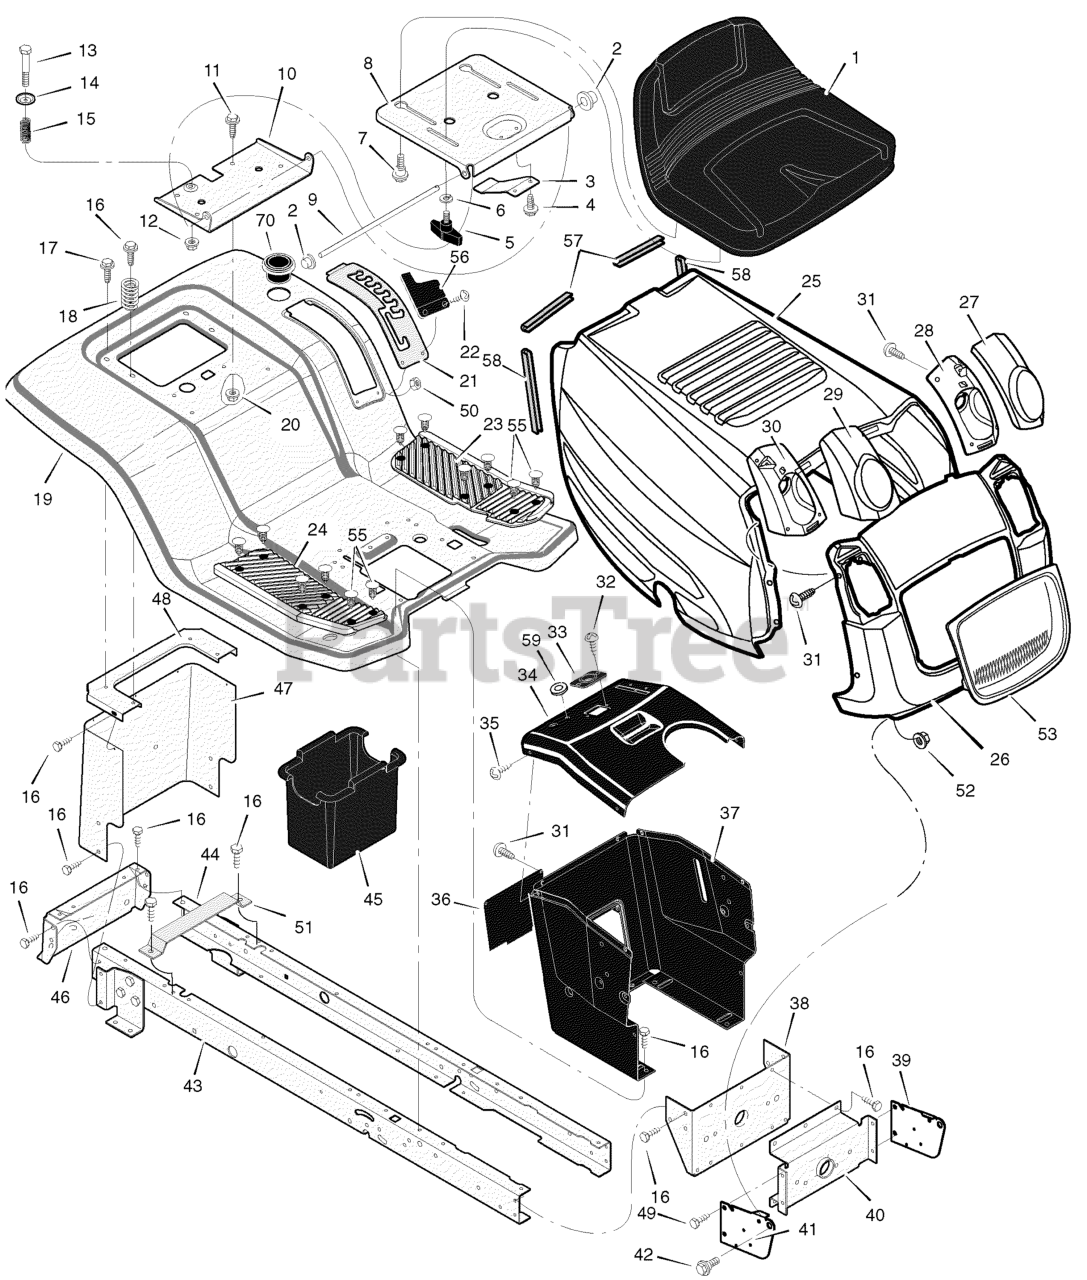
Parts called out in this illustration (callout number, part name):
2	Cap, Push 0n
3	Spring
4	Screw
5	Bolt, Wing
6	Washer
7	Bolt, Shoulder
8	Support, Seat
9	Rod, Pivot
10	Bracket, Pivot
11	Bolt
12	Nut
13	Bolt, Shoulder
15	Spring
16	Screw
17	Screw
18	Spring
19	Deck, Seat
20	Nut
21	Plate, Index
22	Screw
23	Mat, Left
24	Mat, Right
27	Lens, Left
28	Housing, Left Headlamp
29	Lens, Right
30	Housing, Right Headlamp
31	Screw
33	Bearing, Steering
35	Screw
36	Panel, Access
37	Support, Dash
38	Bracket, Rear Hanger
39	Support, Left Grille
40	Axle, Hanger
41	Support, Right Grille
42	Bolt, Shoulder
43	Frame, Right
44	Frame, Left
45	Container, Battery
46	Plate, Hitch
47	Plate, Rear -Electric Lift
48	Top, Rear Plate
49	Screw
50	Nut
51	Bracket, Battery Support
53	Insert, Grille
55	Fastener, Panel
56	Cover, Detent
57	Trim, Hood (3.75")
58	Trim, Hood (6.5")
59	Grommet, Parking Brake
70	Holder, Cup
